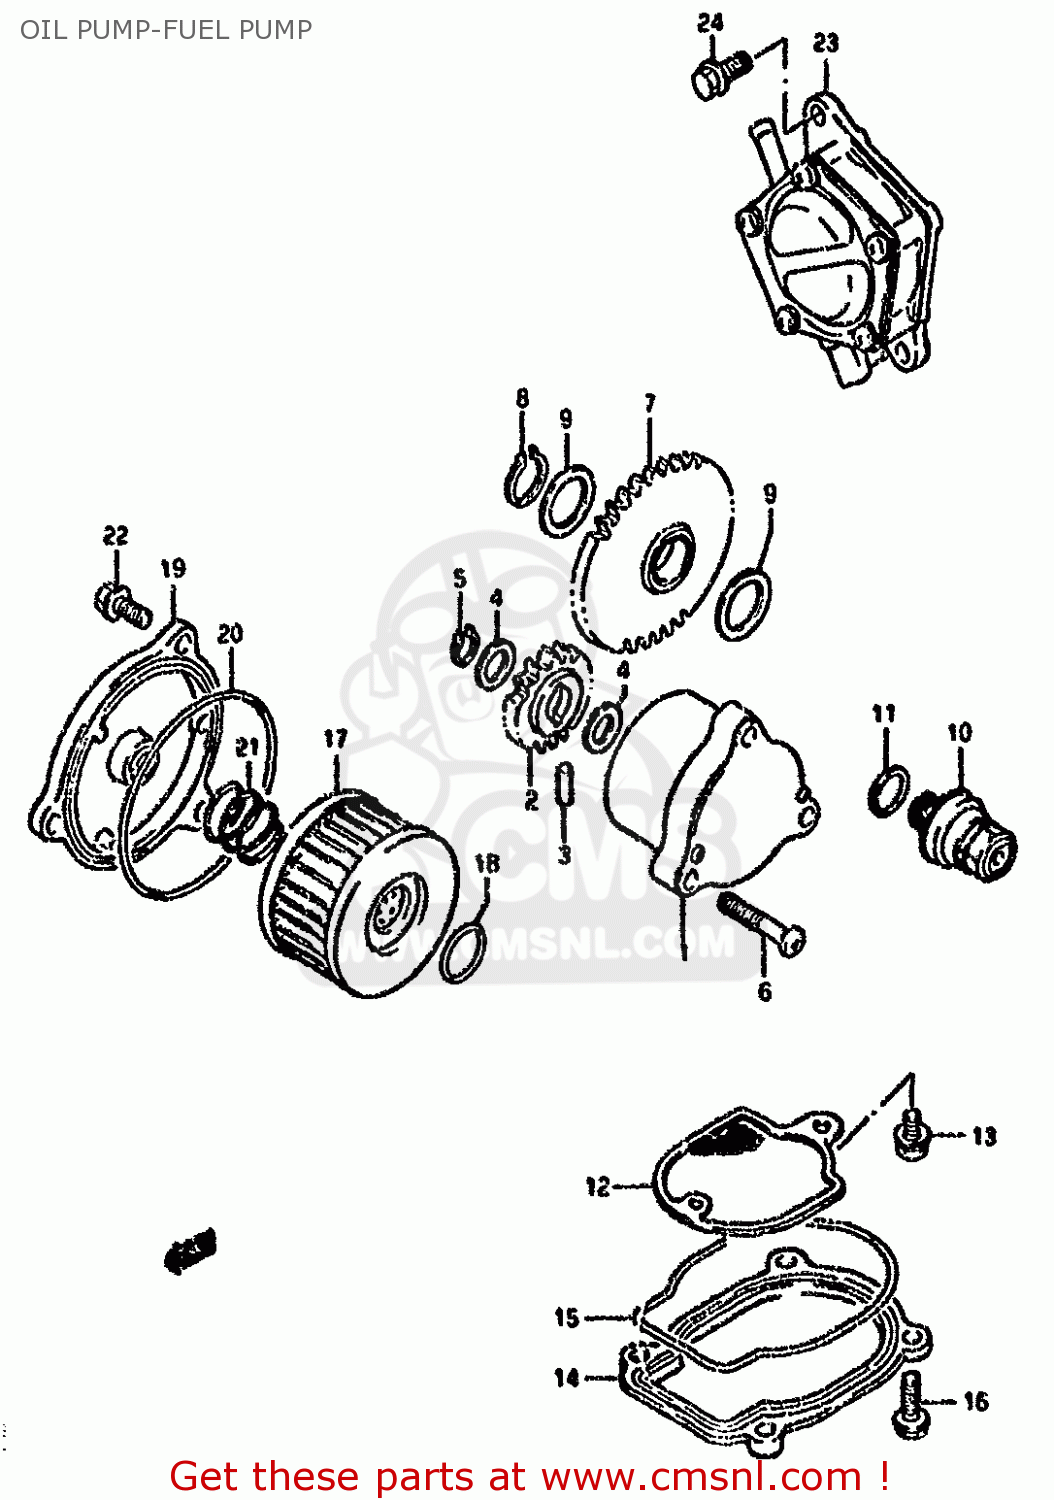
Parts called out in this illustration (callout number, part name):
1	PUMP ASSY,ENGINE OIL
2	GEAR,OIL PUMP DRIVEN(NT:15)
3	PIN(4X15.8)
4	SHIM
5	CIRCLIP,10MM
6	SCREW
7	GEAR,OIL PUMP DRIVE
8	CIRCLIP
9	WASHER
10	VALVE ASSY, OIL RELIEF
11	WASHER
12	STRAINER,ENGINE OIL
13	SCREW
14	CAP,OIL STRAINER
15	O RING,OIL STRAINER CAP
16	BOLT
17	FILTER,ENGINE OIL
18	O RING(D:2.4,ID:15.8)
19	CAP,OIL FILTER
20	O RING(D:2.4,ID:73)
21	SPRING
22	BOLT
23	PUMP ASSY,FUEL
24	BOLT
